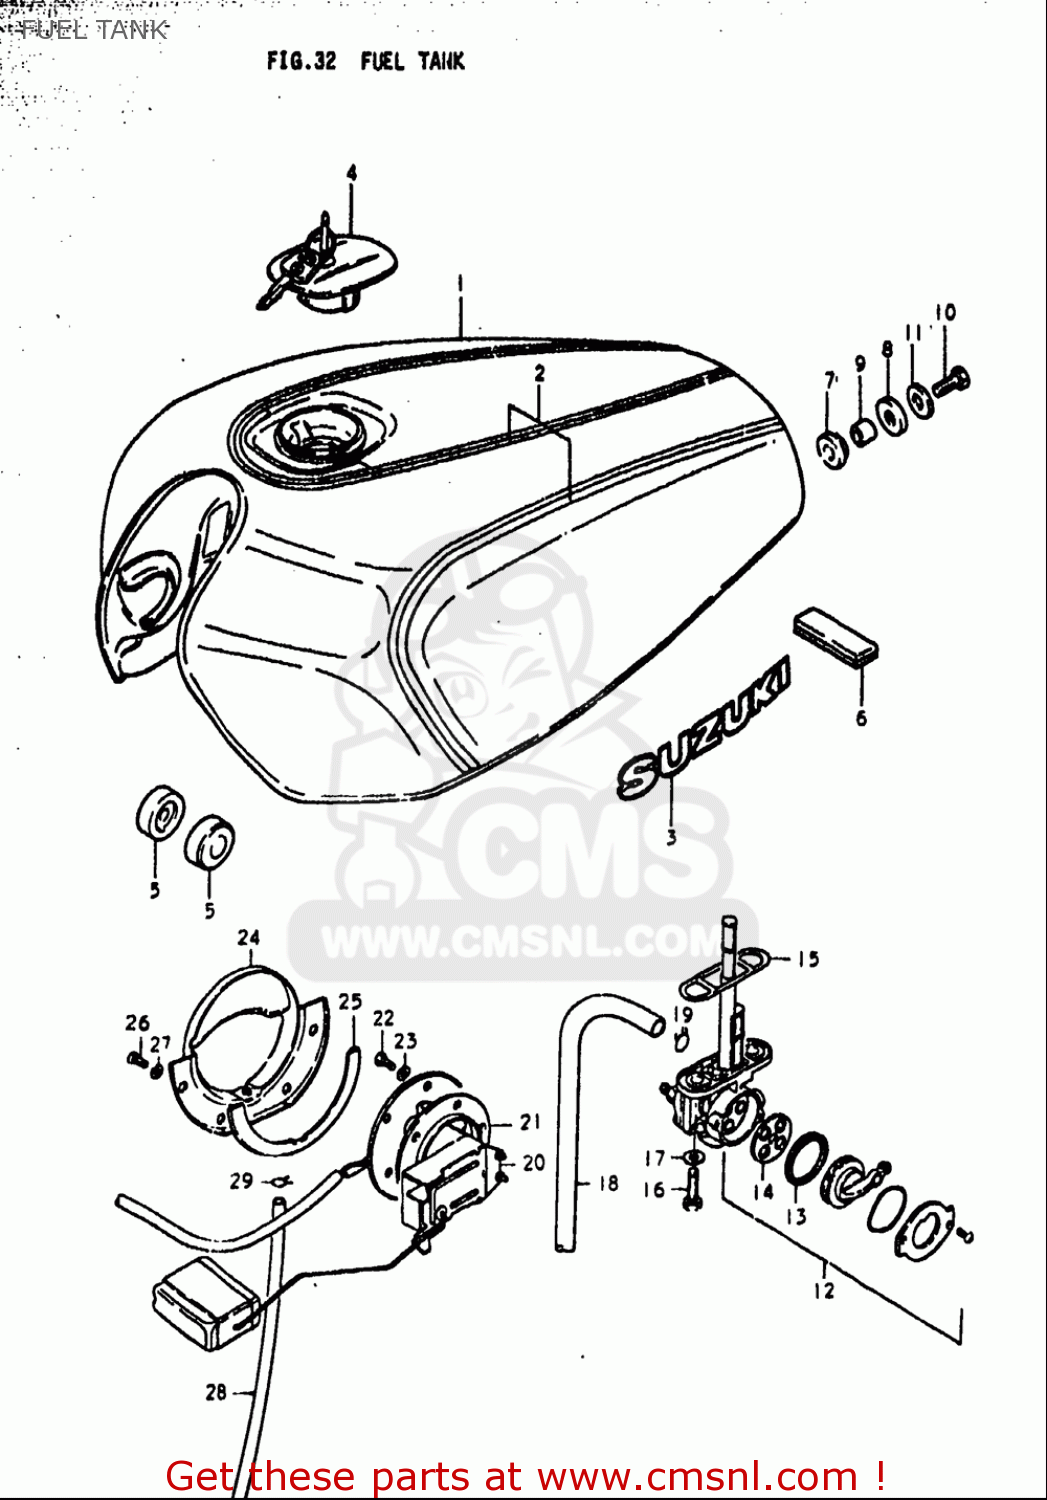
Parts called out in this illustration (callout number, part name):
1	TANK ASSEMBLY,FUEL
3	EMBLEM
4	CAP SET,FUEL TANK
5	CUSHION
6	CUSHION
7	CUSHION
8	CUSHION
9	SPACER(8.5X12X19)
10	BOLT
11	WASHER(8.5X28X1.6)
12	COCK ASSY,FUEL
13	V SEAL,FUEL COCK
14	GASKET (NAS)
15	GASKET, FUEL COCK (NAS)
16	BOLT(6X20)
17	GASKET(5.8X13X1.2) (NAS)
18	HOSE(7X10.2X2000)
19	CLIP
20	GAUGE ASSEMBLY,FUEL LEVEL
21	GASKET,FUEL LEVEL GAUGE (NAS)
22	BOLT
23	WASHER,LOCK
25	GASKET,FUEL DRAIN PLATE (NAS)
26	SCREW(5X6)
27	WASHER,LOCK
28	HOSE(5X8.2X2000)
29	CLIP
